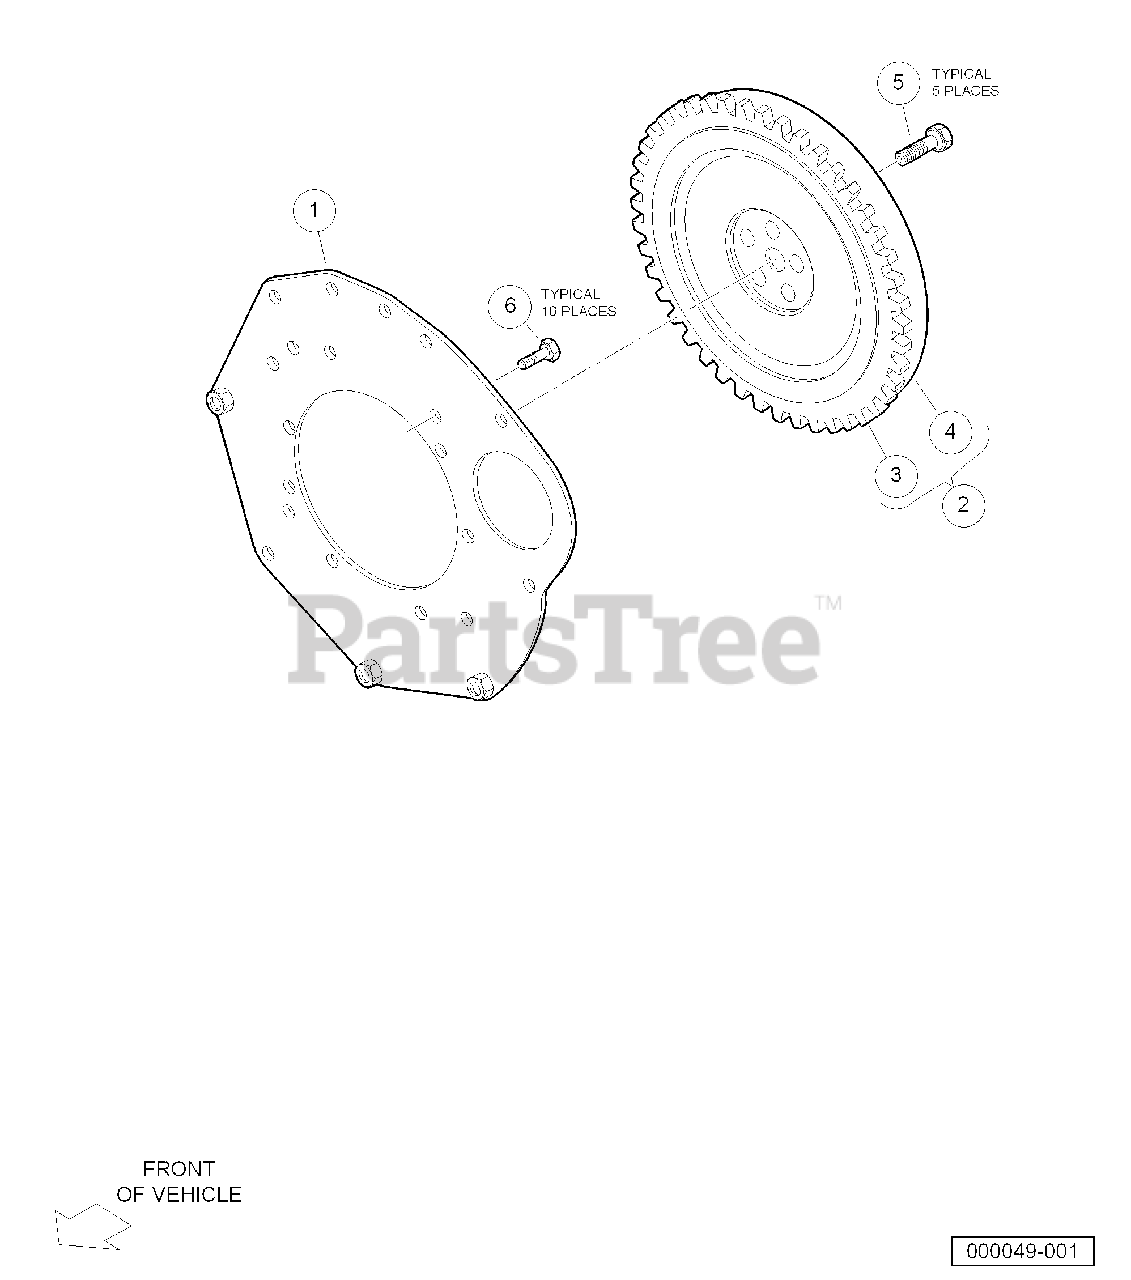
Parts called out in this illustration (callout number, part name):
1	Plate, Rear End
2	Flywheel
3	Gear, Ring, D722
4	Flywheel
5	Bolt, Flange Head, M10 X 1.5 X 25
6	Bolt, End Plate
